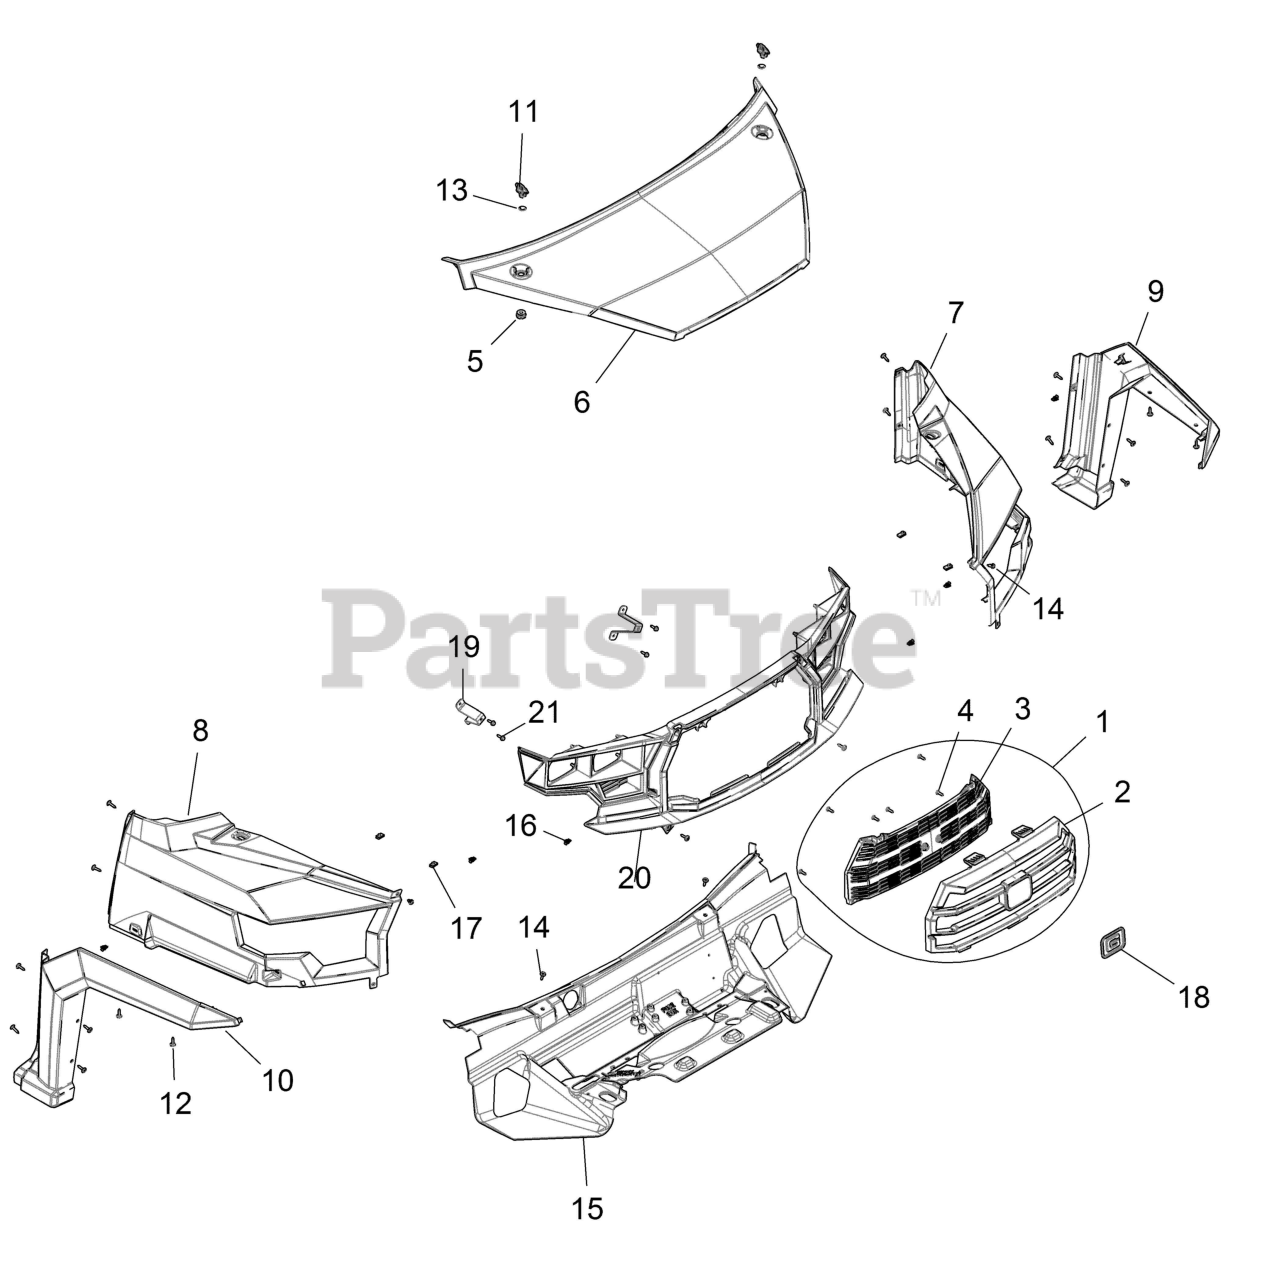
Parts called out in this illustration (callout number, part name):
1	ASM., GRILL, GRAVELY
2	GRILL, FRONT, UPPER, BLACK
3	GRILL, UPPER, TRIM
4	SCR-TXPH-#14 X .75 HI-LO RIE
5	GROMMET-LATCH
6	HOOD-ARIENS,INDY RED
7	FENDER-FRONT,LH,ARIENS,I RED
8	FENDER-FRONT,RH,ARIENS,I RED
9	FLARE, FENDER, FRONT LH
10	FLARE, FENDER, FRONT RH
11	LATCH, 1/4 TURN
12	SCR-TXTH-M6X1.0X25 RIE
14	RIVET-TUFLOK,.315-.325X.787 (5
15	LINER-HOOD,BLK
16	CLIP, DASH TRIM METAL
17	CLIP-U SPEED NUT
19	BRKT-FASCIA MOUNT
20	BEZEL-HEADLIGHT
21	SCR-M6X1.0X20,HXHD,FLG,TDFM,BL
